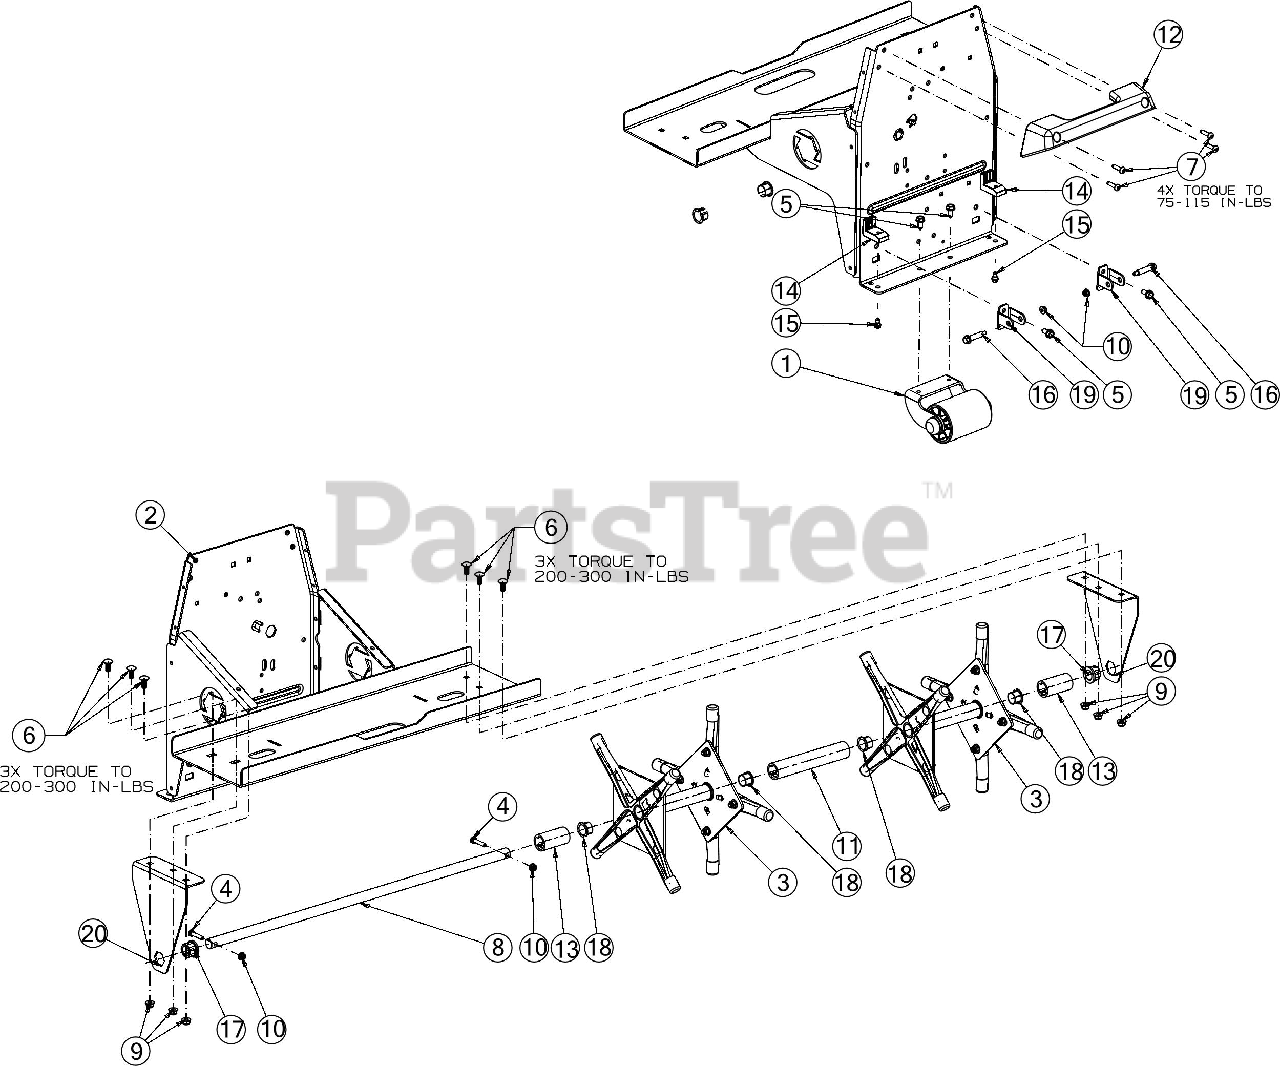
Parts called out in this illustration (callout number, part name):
1	ROLLER BRACKET ASSEMBLY
2	AERATOR FRAME ASSEMBLY
3	AERATOR DOUBLE WELD ASSEMBLY
4	HEX SCREW 1/4-20 x 1.25
5	SCREW 5/16-18 x .750
6	CARRIAGE BOLT 5/16-18 x .75
7	SCREW 1/4-20 x 1.0
8	CORE AERATOR AXLE
9	FLANGE LOCK NUT 5/16-18
10	FLANGE LOCK NUT
13	SPACER - .75 x 1.25 x 2.4
14	BUMPER PAD
15	SHOULDER SCREW 1/4-20 x .50
16	SHOULDER SCREW
17	FLANGE BEARING
18	FLANGE BUSHING
19	SUPPORT BRACKET
20	AXLE SUPPORT BRACKET
